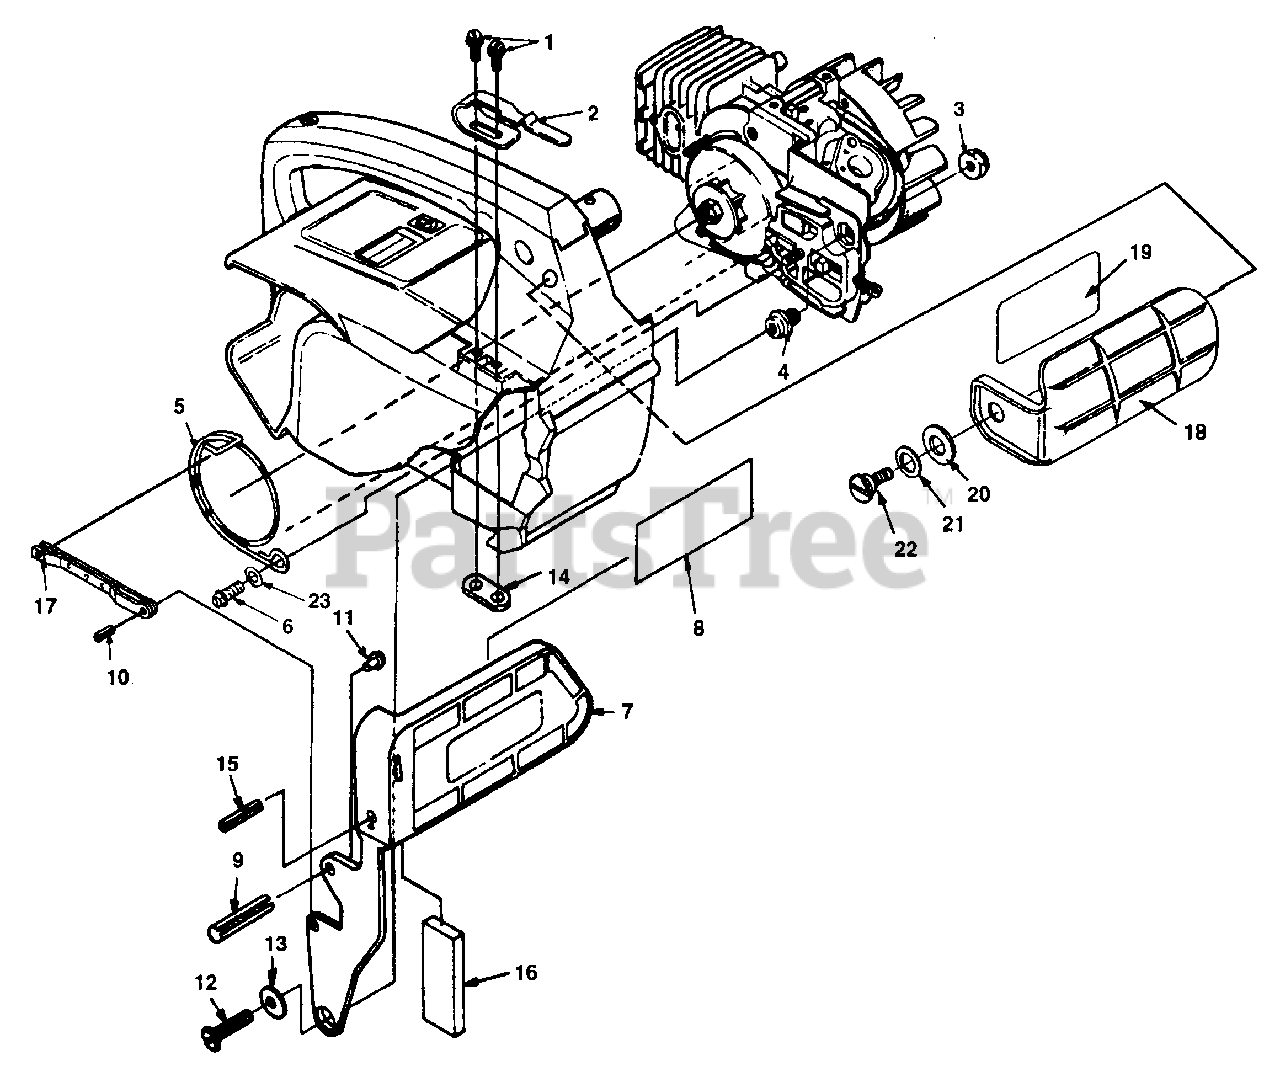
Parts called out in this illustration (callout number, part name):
1	SCREW - Hex Hd. w/Washer (8-32 X 1/2")
2	CLIP - Retaining
3	NUT - Hex, Jam
4	POST - Chain Brake
5	BAND - Brake
6	SCREW - Thread Form (10-24 x 3/4")
7	HANDGUARD & LEVER (200, Super 2 SL)
8	DECAL - Safety
9	PIN - Roll (3/16 X 1")
10	PIN - Roll
11	SCREW - Drive
12	SCREW - Machine, Pan Hd. (10-32 X 1/2")
13	WASHER - Flat
14	NUT - Weld
15	PIN - Roll
16	WEIGHT - Handle
17	PIVOT - Link
18	HANDGUARD KIT (Super 2, XL, 180 & 192 )
19	DECAL - Handguard
20	WASHER - Curve Spring
21	WASHER Flat
22	SCREW - Shoulder
23	WASHER - Flat (#10)
